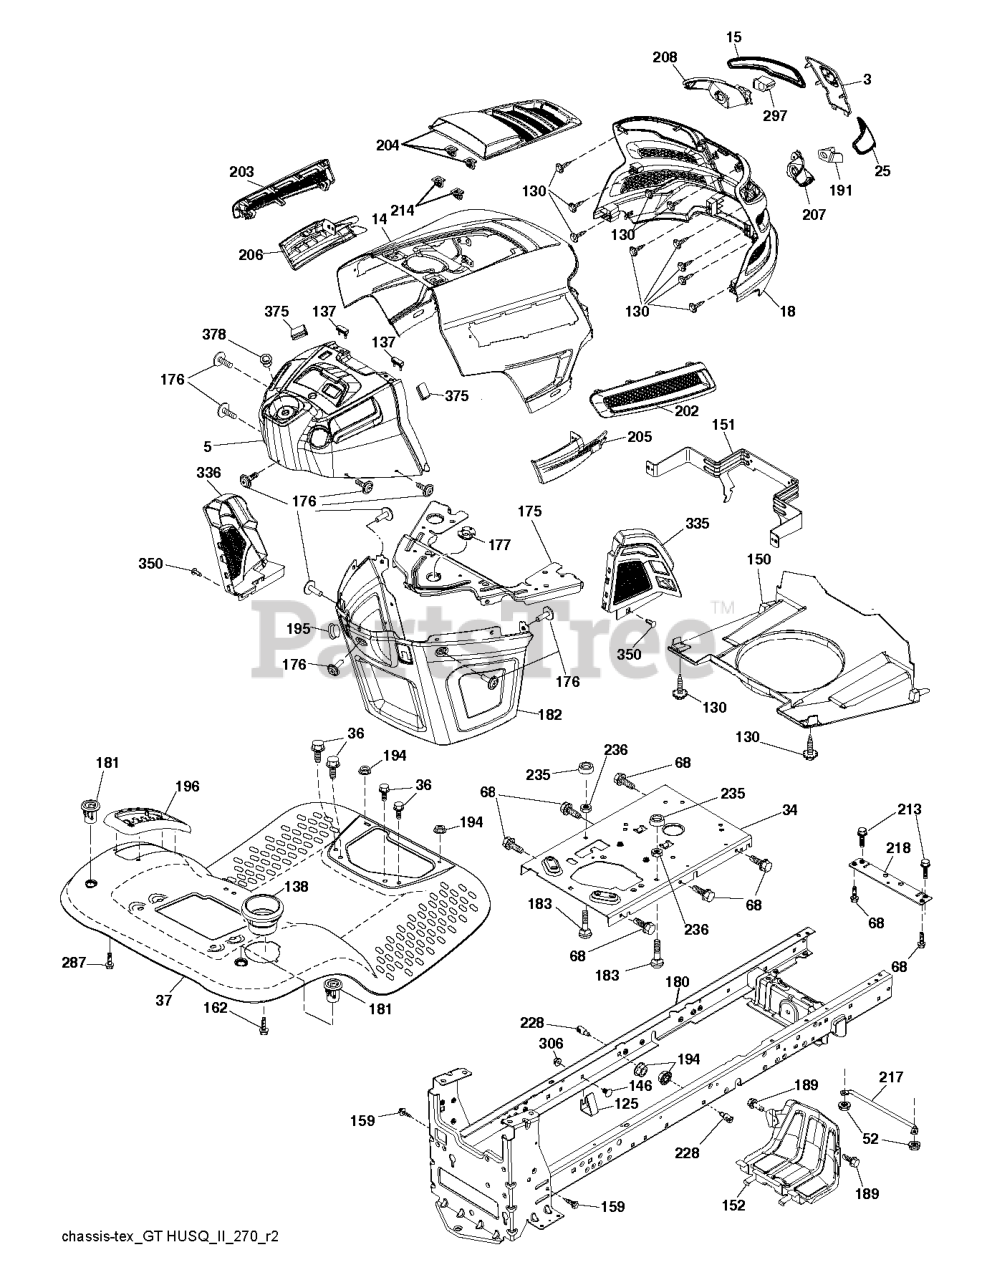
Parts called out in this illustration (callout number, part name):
3	APPLIQUE.SUBASM.GT.HUSQ.II
5	DASHBOARD.UPPER.ASM.GT2.X498
14	HOOD.ASM.HUSQVARNA.GT.TEX.ORAN
15	LENS.HEADLIGHT.LH.GTII.2011
18	GRILLE SUBASM.GT.II.LOW.HDLGHT
25	LENS.HEADLIGHT.RH.GTII.2011
34	PLATE.ENGINE.WELDED.CHASSIS
36	SCREW 5/16"
37	FENDER.TLT.FS.W/CUPHLD.ORANGE
125	CLIP.FUEL.LINE
137	BUMPER DASH
138	HOLDER.CUP.LT.GREY
146	BOLT.RDHD.SHT.SQNK.3/8-16X5/8
150	AIR.DUCT.GTV2(2.54"RING HEIGHT
151	BRACKET.PIVOT.HOOD.GT.HUSQ.II
152	SHIELD.BROWNING.PNT.GT.V2
159	SCREW, 3/8-16X3/4
175	PLATE.PNT.CROSSMEMBER.HUSQ/PRE
176	SCREW.#10-24X5/8.RN.QU
177	BUSHING STEERING
180	CHASSIS
181	BUSHING.MNT.FEND.CRGO.TEX.49
182	DASH LOWER.HUSQ.PRED NO CRUISE
189	SCREW
191	INSERT.REFLECTIVE.RH.HUSQ.GTII
195	PLUG.HOLE.DASH.LOWER.12V.BLK
196	DECKLFT.CONSOL FULL ASSM GREY
202	VENT.SIDE.RH.GT.HUSQ.II.
203	VENT.SIDE.LH.GT.HUSQ.II.498
204	VENT.TOP.ASM.HUSQ.GT2
205	SIDE.TRIM.RH.GT.HUSQ.II
206	SIDE.TRIM.LH.GT.HUSQ.II.GRAY
207	HEADLIGHT.CUP.BEZEL.HUS.GT2.RH
208	HEADLIGHT.CUP.BEZEL.HUS.GT2.LH
213	SCREW HEXAGON HEAD SCREW 5/16-
214	CLIP.RETAINER.TINNER.
217	ROD.PIVOT.HOOD
218	X-PIECE.HOOD.STOP.NON/
228	STUD.W/"D"ANTI-ROTATION
236	NUT.CENTERLOCK.5/16-
287	SCREW 1/4X20
297	INSERT.REFLECTIVE.LH.HUSQ.GTII
306	NUT LOCK FLG 3/8-16 UNC
335	COVER.LOWER.DASH.RH.BLACK
336	COVER-LH.LOWER.DASH.GT2.BLACK
350	CLIP.X-MAS.TREE
375	BUMPER CLIP-ON. DASH 1"
378	BUSHING FLANGE; PLASTIC
